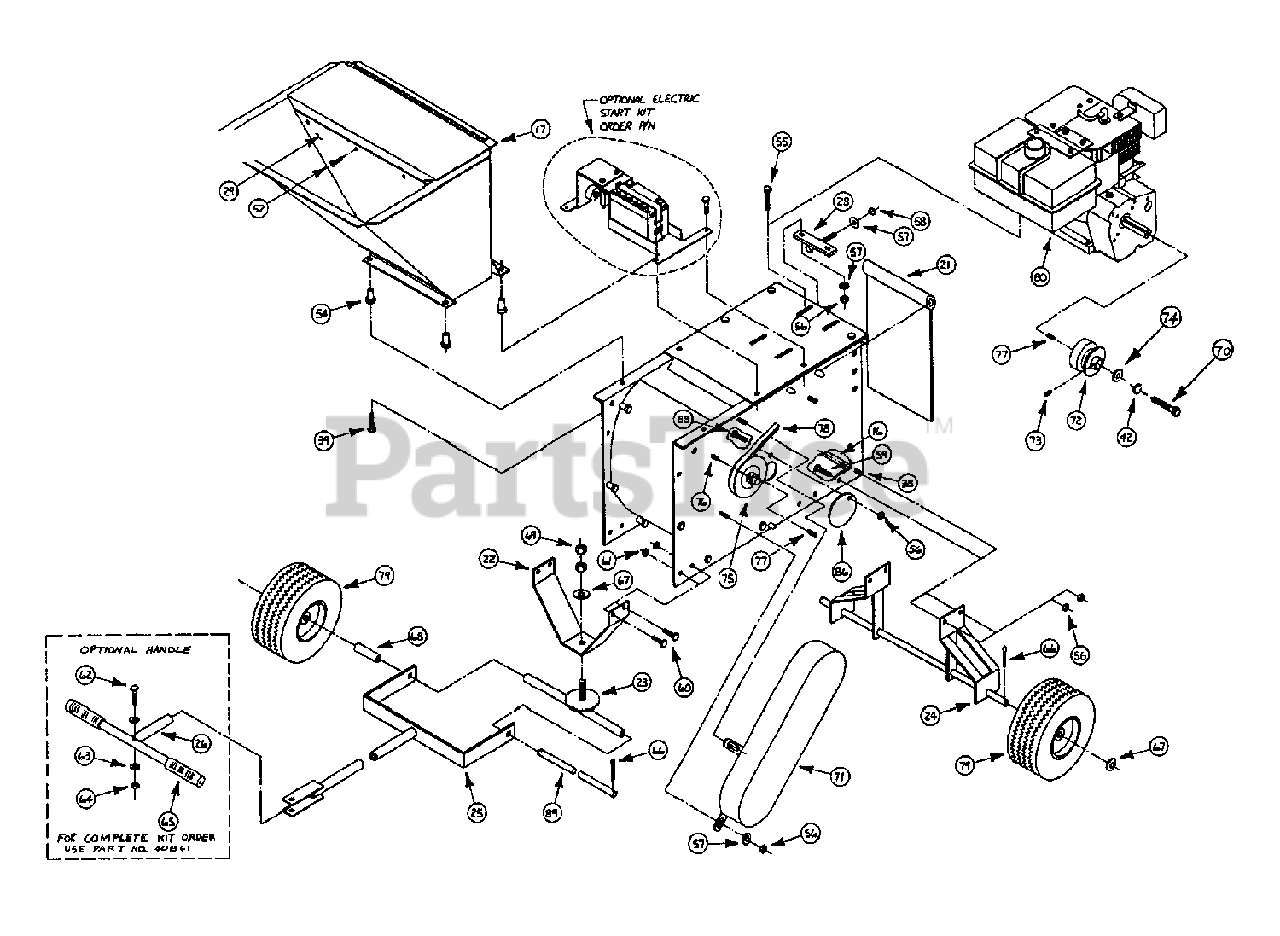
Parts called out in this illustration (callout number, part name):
16	Spacer
17	Hopper
21	Baffle Plate
22	Front Axle Mounting Bracket
24	Axle Bracket
25	Tow Hitch
26	Pull Handle
28	Belt Tensioner
29	Hopper Flex Guard
38	Tie Rod
39	5/16-18 x 1-1/4 Hex Hd. Cap Screw GR 5
42	Washer, 7/16" Internal Lock
52	Push Button
54	Vibration Dampner
55	5/16-18 x 2 Hex Hd. Cap Screw Pltd.
56	5/16-18 Grip-Co Lock Nut Pltd.
57	5/16 Flat Washer Pltd.
58	5/16-18 Flex Lock Nut Pltd.
59	5/16-18 x 3/4 Hex Hd. Cap Screw Pltd.
60	3/8-16 x 3/4 Hex Hd. Cap Screw Pltd.
61	3/8-16 Grip-Co Lock Nut Pltd.
62	3/8-16 x 1-1/2 Hex Hd. Cap Screw Pltd.
63	3/8 Flatwasher Pltd.
64	3/8-16 Flex Lock Nut Pltd.
65	Handle Grip
66	1/8 x 1-1/4 Cotter Pin
67	5/8 Flatwasher Pltd.
68	Axle Spacer
69	5/8-11 Hex Nut Pltd.
70	7/16-20 x 3/4" Hex Hd. Cap Screw
71	Belt Guard
72	Clutch
73	Set Screw (Used on early clutch only)
74	Flatwasher 7/16"
75	Rotor Pulley
76	5/16-18 x 5/16 Set Screw
77	1/4 x 1/4 x 1 Shaft Key
78	Belt 4L-450
79	Wheel 10.5 x 3.50
86	Cover Plate
88	5/16-18 x 5/8 Hex Hd. Cap Screw
89	Axle Rod
